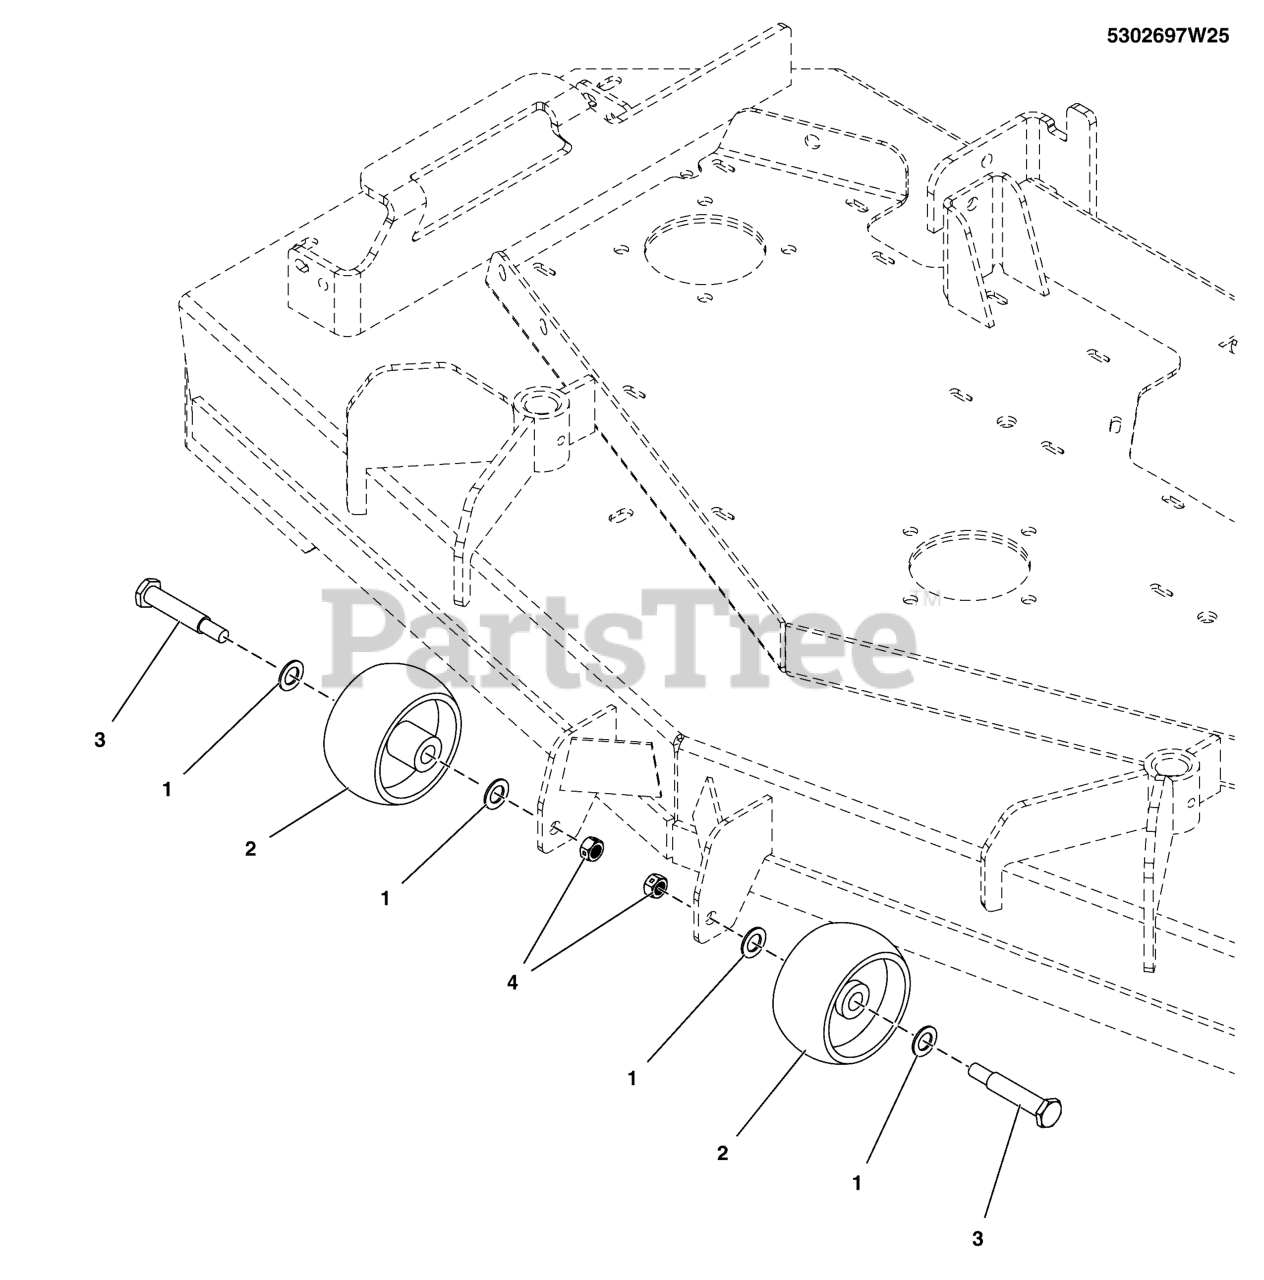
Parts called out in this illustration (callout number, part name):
1	WASHER,.516IDX.875ODX.06,FLAT,ZC/CL
2	WHEEL- 2.00 WIDE 3.88 DIA 0.531ID POLY
3	BOLT-WHEEL 3/8-16X2.781 .750 THRD
4	NUT, 3/8-16 HEX SIDE LOCK
